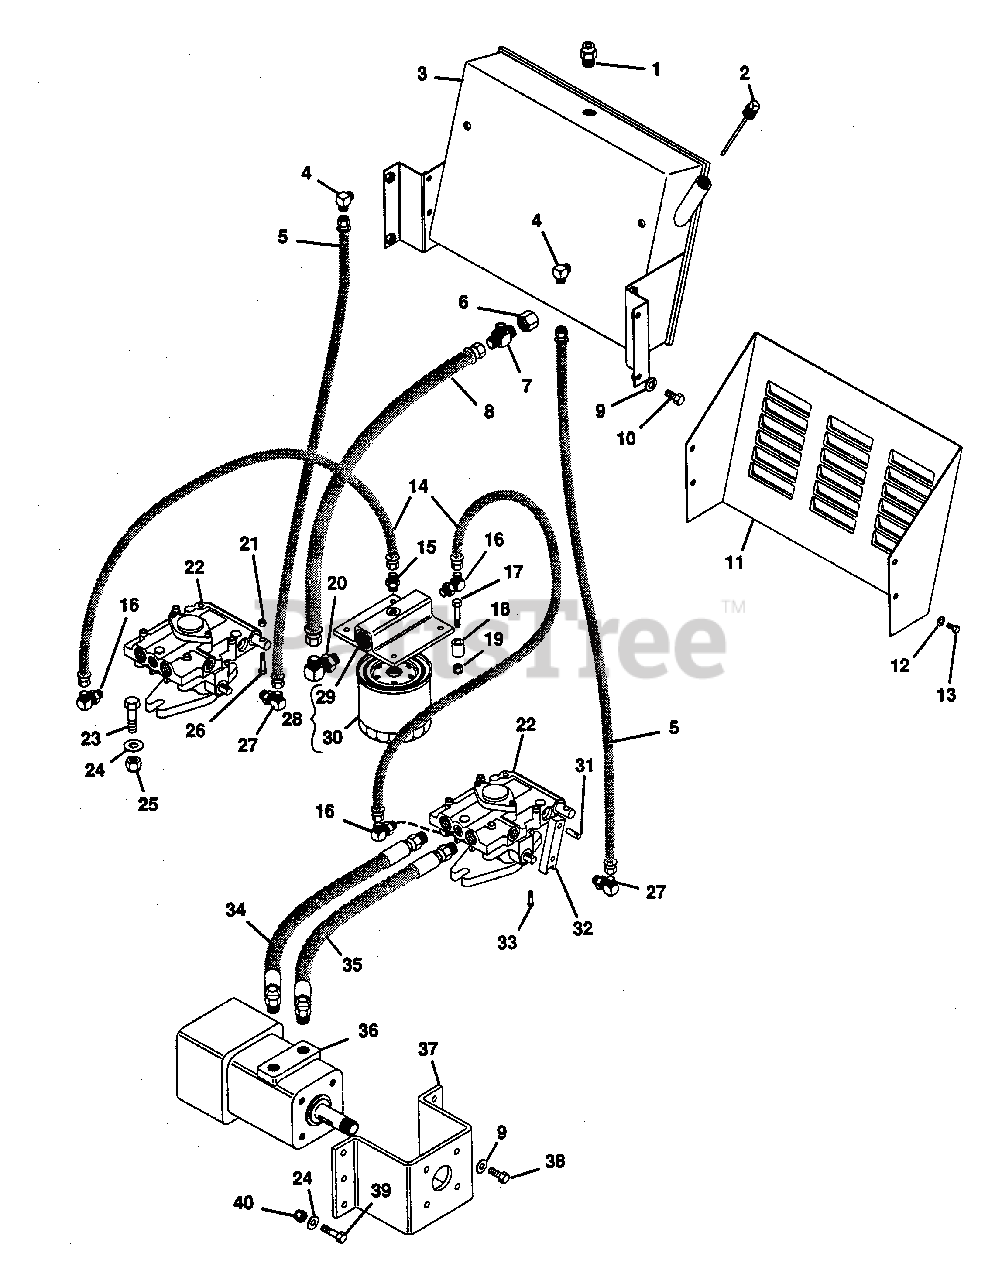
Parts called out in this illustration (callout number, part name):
1	Plug, 1/8 Vent
2	Gauge, Hydraulic Tank Level
3	Tank, Hydraulic Oil
4	Adaptor, 2501-6-4 90 Deg. Elbow
5	Hose, Hyd. Valve to Tank
6	Capnut, 304-C-8
7	Adaptor, 2601-8-8-6 Side Tee
8	Hose, Tank to Filter
9	Washer, Lock 3/8 Reg.
10	Bolt, Hex 3/8-16x.75
11	Shield, Heat
12	Washer, Lock 114 Reg.
13	Bolt, Hex 1/4-20x.50
14	Hose, Oil Filter to Pump
15	Adaptor, 0503-4-4
16	Adaptor, 2503-4-4
17	Bolt, Hex 5/16-18x2.00
18	Bush., St..328x.462x1.00 Stl.
19	Nut, Lock 5/16-18
20	Adaptor, P-H #2503-8-8
21	Nut, Lock 1/4-20
22	Pump, Variable Displace
23	Bolt, Hex 3/8-16x1.125
24	Washer, Flat .406x.812x.065
25	Nut, Lock 3/8-16
26	Bolt, Hex 1/4-20x1.75
27	Adaptor, 2503-6-6
28	Assembly, Spin-On Lube
29	Assembly, Head
30	Element
31	Pin, Dowel
32	Arm, Pump Actuating
33	Screw, Cap 10-24x.75 Hex Socket
34	Asm, Hose Wheel Motor to Pump
35	Asm, Hose Wheel Motor to Pump
36	Motor, Hydraulic Wheel
37	Bracket, Wheel Motor
38	Bolt, Hex 3/8-16x.875
39	Bolt, Hex 3/8-16x1.00
40	Nut, Lock 3/8-16
